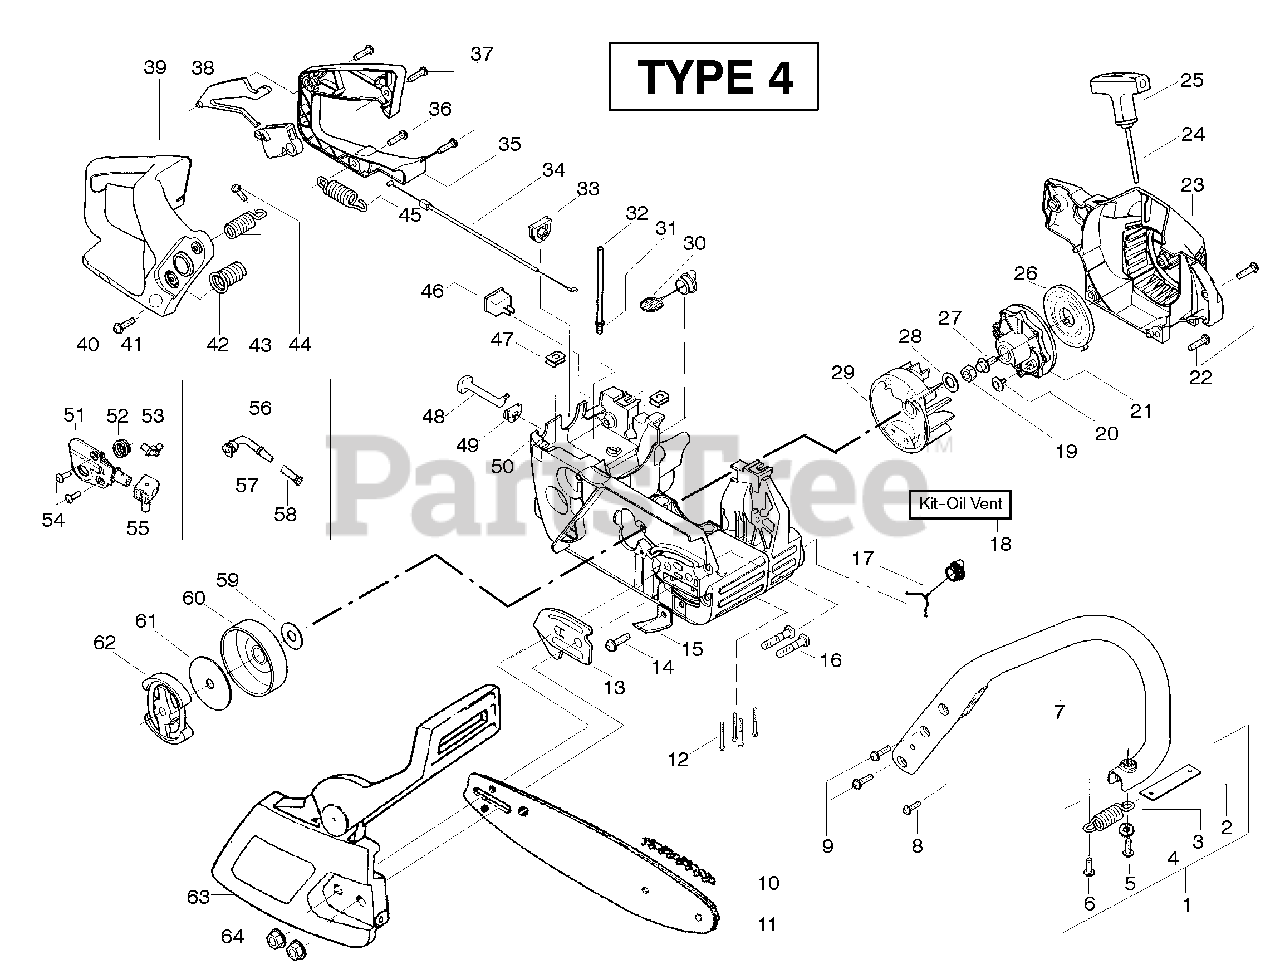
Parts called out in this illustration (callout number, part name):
1	Assy.- Isolator
2	Limiter Strap
3	Spring- Isolator
4	Washer
7	Handle-Front
10	Chain-16"
11	Bar-16" Quick Adjust
13	Plate-Bar Mounting
15	Chain Catcher
16	Bolt-Bar
17	Assy-Oil Cap
18	Kit-Oil Check Valve
19	Nut- Flywheel
21	Starter Pulley
23	Assy-Fan Housing
24	Kit - Rope
25	Handle-Starter
26	Spring-Recoil
28	Washer- Flywheel
29	Assy- Flywheel
30	Assy-Fuel Cap
31	Fitting- fuel line
32	Kit-Fuel line (large)
33	Grommet-Cable
34	Cable-Throttle
35	Cover-Rear Handle
38	Throttle Lockout
39	Trigger-Throttle
40	Handle - Rear
42	Assy. Isolator - lower
43	Kit- Isolator (Upper)
45	Spring- Isolator
46	Kit-Switch
47	Nut- "U"-Type
48	Knob-Choke
49	Grommet-Knob
50	Assy-Chassis
51	Kit - Oil Pump
52	Gear-Worm Spring
53	Elbow-Oil Pickup
55	Seal Block
56	Assy-Oil Pickup
57	Pickup-Oiler
58	Filter-Oil
59	Washer-Thrust
60	Assy.-Clutch Drum w/bearing
61	Washer-Clutch
62	Assy. Clutch
63	Assy-Chain Brake
64	Nut-Bar Mounting
